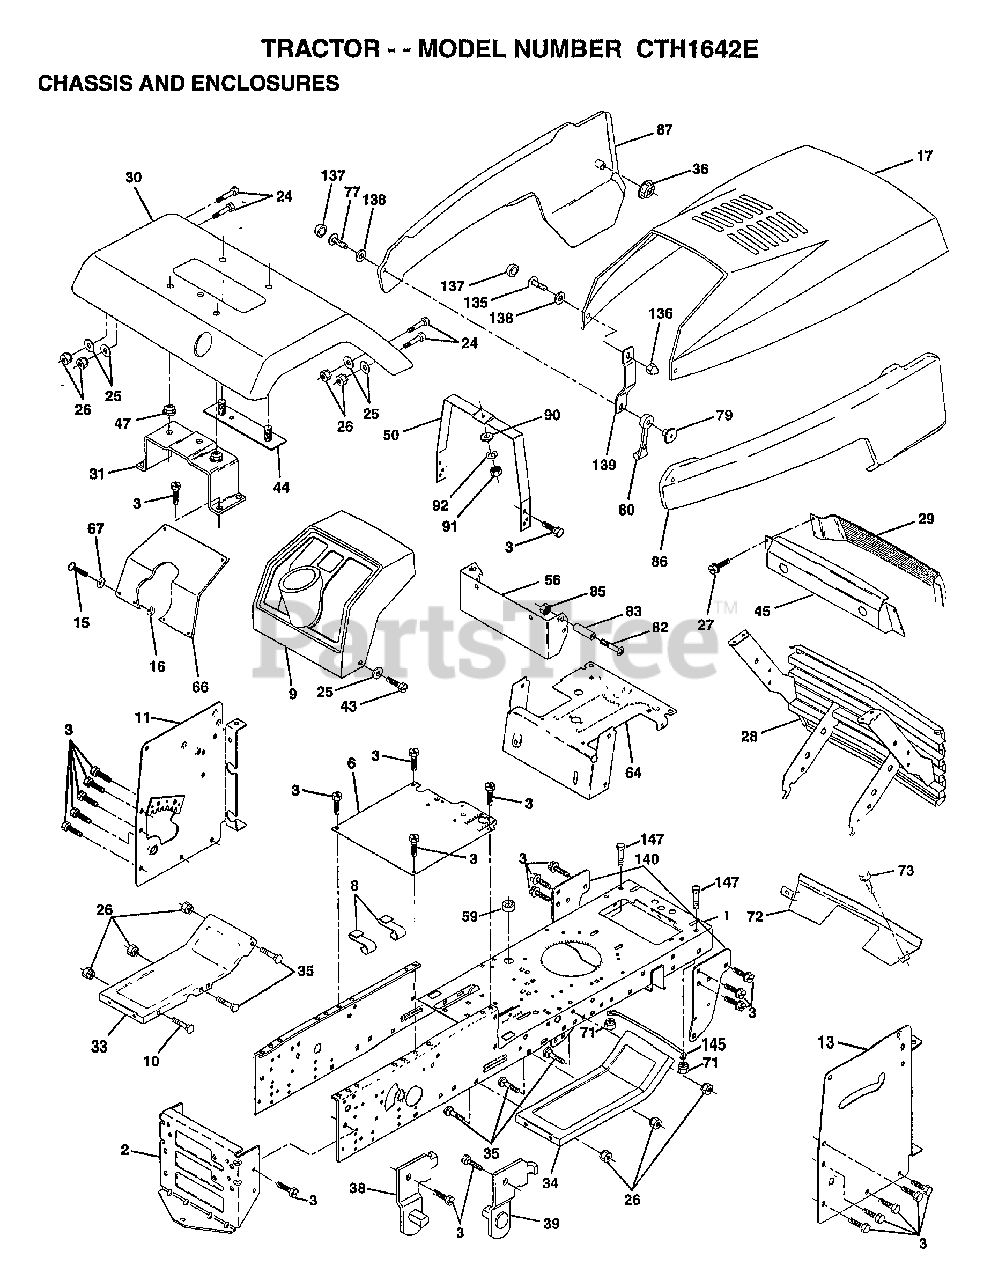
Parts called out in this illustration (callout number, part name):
1	CHASSIS ASM
3	SCREW
6	SADDLE
8	"CLIP,INSULATOR"
9	DASHBOARD BLACK
11	PANEL.DASH.LH.PNT
13	PANEL.DASH.RH.
15	SCREW
17	HOOD PNT YARDPRO
24	BOLT
25	WASHER
26	NUT
28	GRILLE ASM PNT
29	LENS.BAR.CLEAR
30	FENDER PNT
31	BRKT.ASM.FENDER
33	FOOTREST.LH.LT/GT
34	FOOTREST.RH.LT/GT
35	BOLT
36	PAL NUT LT
38	BRACKET ASM LH
39	BRACKET ASM RH
43	SCREW GTV
44	STRAP ASM FENDER
45	BEZEL.ASM.
47	NUT-PUSH YT
50	DASH.SUPT.YP/HUSQ
56	EXT DASH LTYT
64	DASH.LOWER.LT
66	"PLATE-DASH,SLKSCR"
67	WASHER
72	STRAP.PNT.GRILLE
73	SCREW CRT
77	SCREW
79	WELDNUT
80	HOOD LATCH T
82	SCREW
83	SPACER LT
86	PANEL PNT RH SIDE
87	PANEL PNT LH SIDE
90	WASHER PM
92	LOCKWASHER
135	SCREW.10-24X3/8.
136	ACORN NUT RB
137	SNAP CAP LT
138	WASHER LT
139	BKT.SPT.HOOD/PANL
140	BRKT SUSPENSION
145	"ROD POVOT,CHASSIS"
147	BOLT LT
